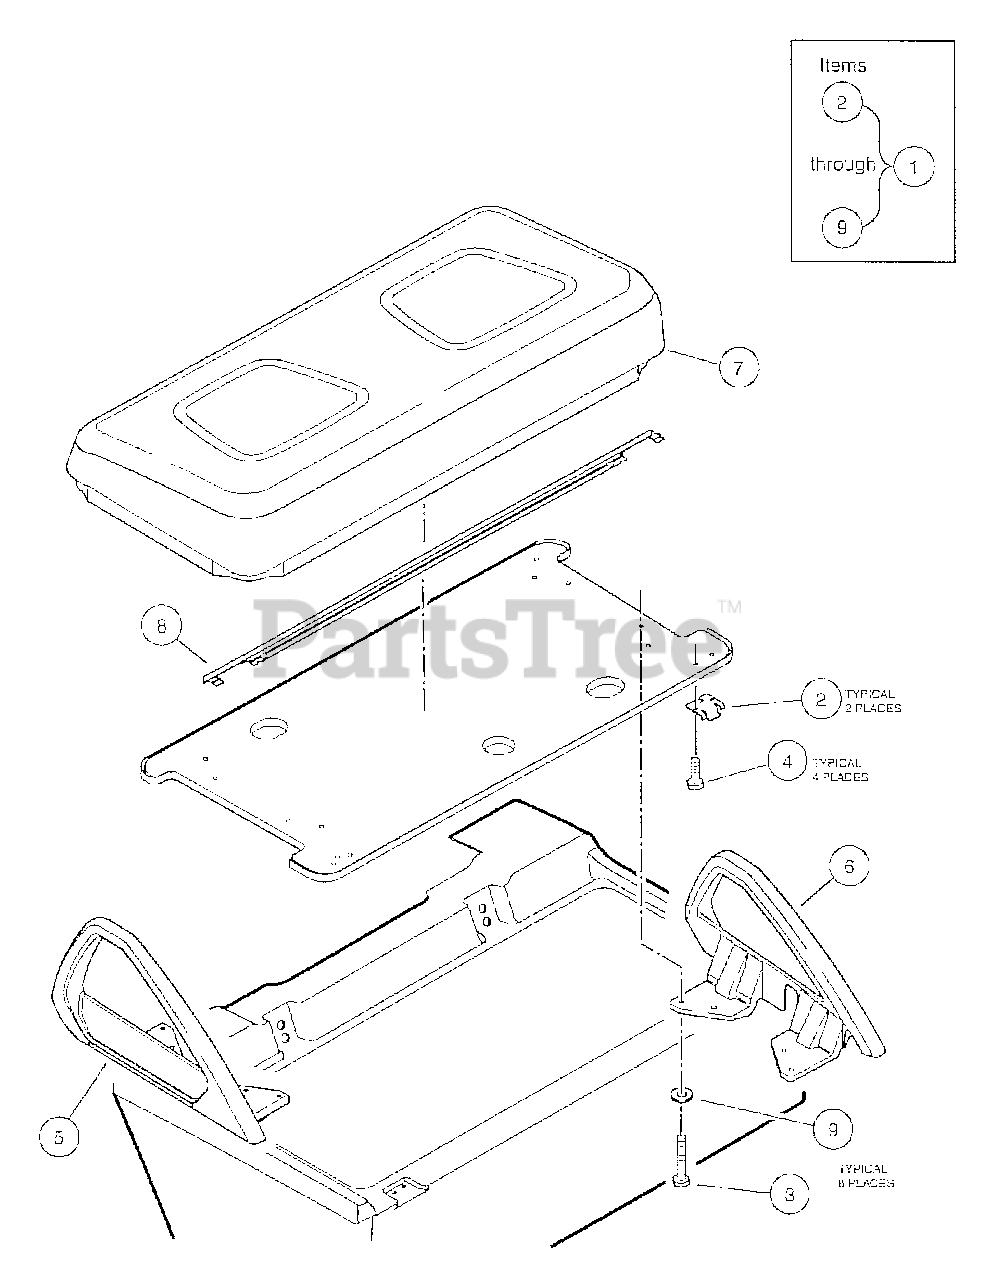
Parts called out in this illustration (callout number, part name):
1	Assembly, Seat, Gray
2	Hinge Plate
3	Screw, 1/4-20 X 1.50 Hex-Head Cap
4	Screw, 1/4-20 X 0.75 Hex-Head
5	Armrest, Passenger (right)
6	Armrest, Driver (left)
7	Vinyl Cover, Gray
8	Gasket, Seat
9	Washer, 1/4 Type A Narrow Flat
